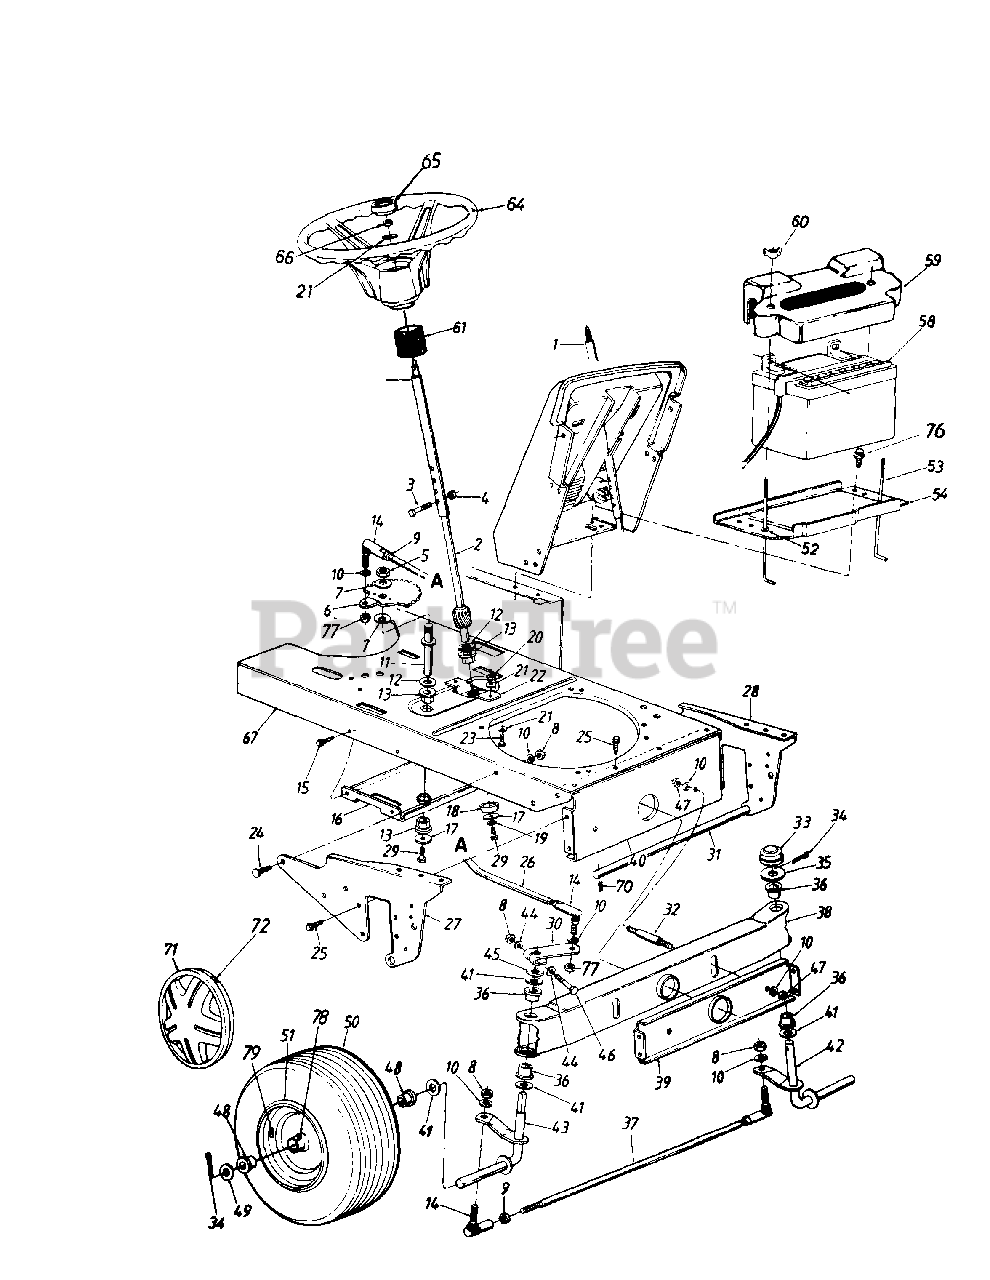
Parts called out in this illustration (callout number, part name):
1	Steering Column Ass'y.
2	Lower Steering Shaft
3	Hex Bolt 1/4-20 x 1.31" Lg.
4	Hex L-Nut 1/4-20 Thd.
5	Hex Nut 5/8-18 Thd.
6	Steering Gear Segment
7	Bell-Wash. 5/8" I.D. x 1.25" O.D.
8	Hex Nut 3/8-24 Thd.
9	Hex Jam Nut 3/8-24 Thd.
10	L-Wash. 3/8" I.D.
11	Steering Gear Segment Shaft
12	Fl-Wash..64" I.D. x 1.24" O.D.
13	Hex Flange Brg..63" I.D.
14	Ball Joint Ass'y.
15	Hex Wash. Hd. TT-Tap Scr. 1/4-20 x .5" Lg.
16	Deck Idler Support Brkt.
17	Fl-Wash..33" I.D. x 1.25" O.D.
18	Spacer .985" I.D. x 1.25" O.D.
19	L-Wash. 5/16" I.D.
20	Hex Nut 5/16-24 Thd.
21	Bell-Wash..345" I.D. x .88" O.D.
24	Ribbed Neck Bolt 3/8-24 x .8" Lg.
25	Hex Wash. TT-Tap Scr. 5/16-18 x .62" Lg
26	Steering Drag Link
27	Pivot Bar Side Plate - R.H.
28	Pivot Bar Side Plate - L.H.
29	Hex Bolt 5/16-18 x .62" Lg.
30	Steering Arm
31	Deck Connecting Rod
32	Pivot Bar Shld. Bolt 3/8-16 x 5/8" Lg.
33	Cap
34	Cotter Pin 5/32" Dia.
35	Flat Washer
36	Flange Brg. 757" I.D.
37	Tie Rod 20.25" Lg.
38	Pivot Bar Assy.
41	Fl-Wash. 76" I.D. x 1.49" O.D.
42	Front Axle Ass'y.- L H
43	Front Axle Ass'y.- R H
44	Bowed Washer
45	Spacer 755" I.D. x 1.25" O.D.
46	Hex Bolt 3/8-24 x 2.25" Lg.
47	Hex Nut 3/8-16 Thd.
48	Flange Brg. 75" I.D
49	Fl-Wash. 71" I.D x 1.5" O.D.
51	Rim Only
52	Push Nut
53	Battery Hold Down Rod
54	Battery Plate
58	Battery (275 Cold Crank Amps)
59	Battery Cover
60	Wing Nut Plastic 1/4-20 Thd.
61	Steering Bellow
64	Steering Wheel
65	Steering Wheel Cap
66	Hex L-Nut 5/16-24 Thd
71	Hub Cap
72	Spring Clip
76	Hex AB-Tap Scr. 1/4 x .62" Lg.
77	Hex Jam L-Nut 3/8-24 Thd.
78	Grease Fitting
79	Air Valve
